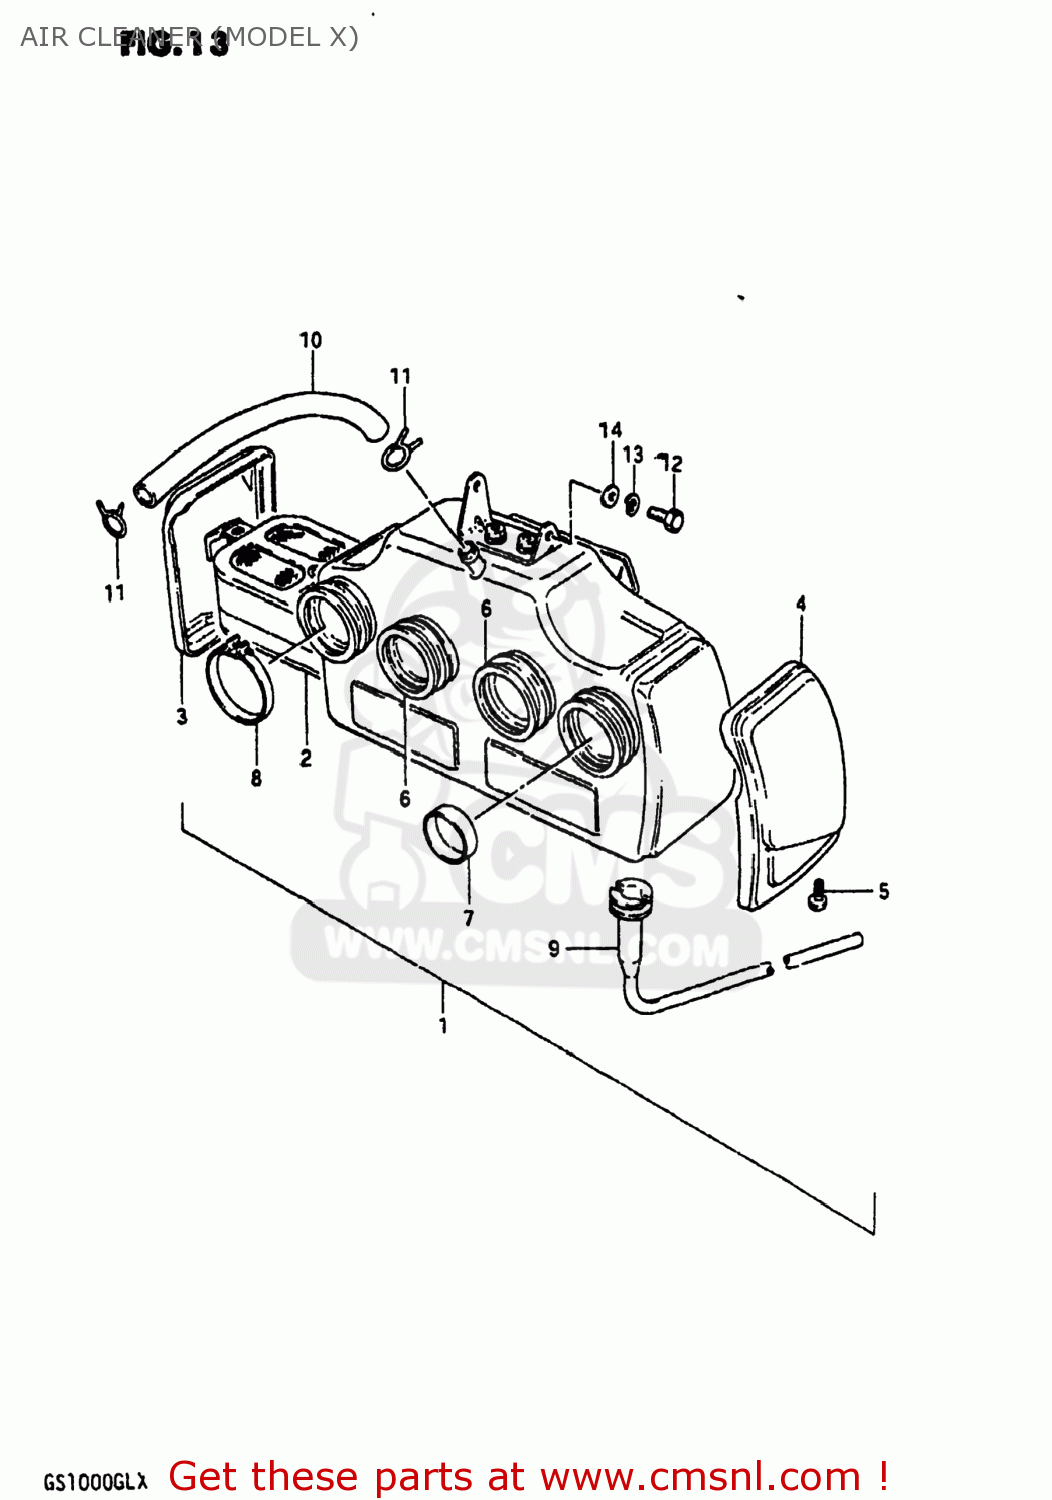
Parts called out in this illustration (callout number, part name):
1	CLEANER ASSEMBLY,AIR
2	FILTER ASSY
3	CAP,AIR CLEANER
4	CAP,AIR CLEANER,LEFT
5	SCREW
6	TUBE,OUTLET
7	RING,CARBURETOR AIR IN
8	CLAMP
9	DRAIN TUBE
10	TUBE,BREATHER
11	CLIP
12	BOLT
13	LOCK WASHER
14	WASHER
